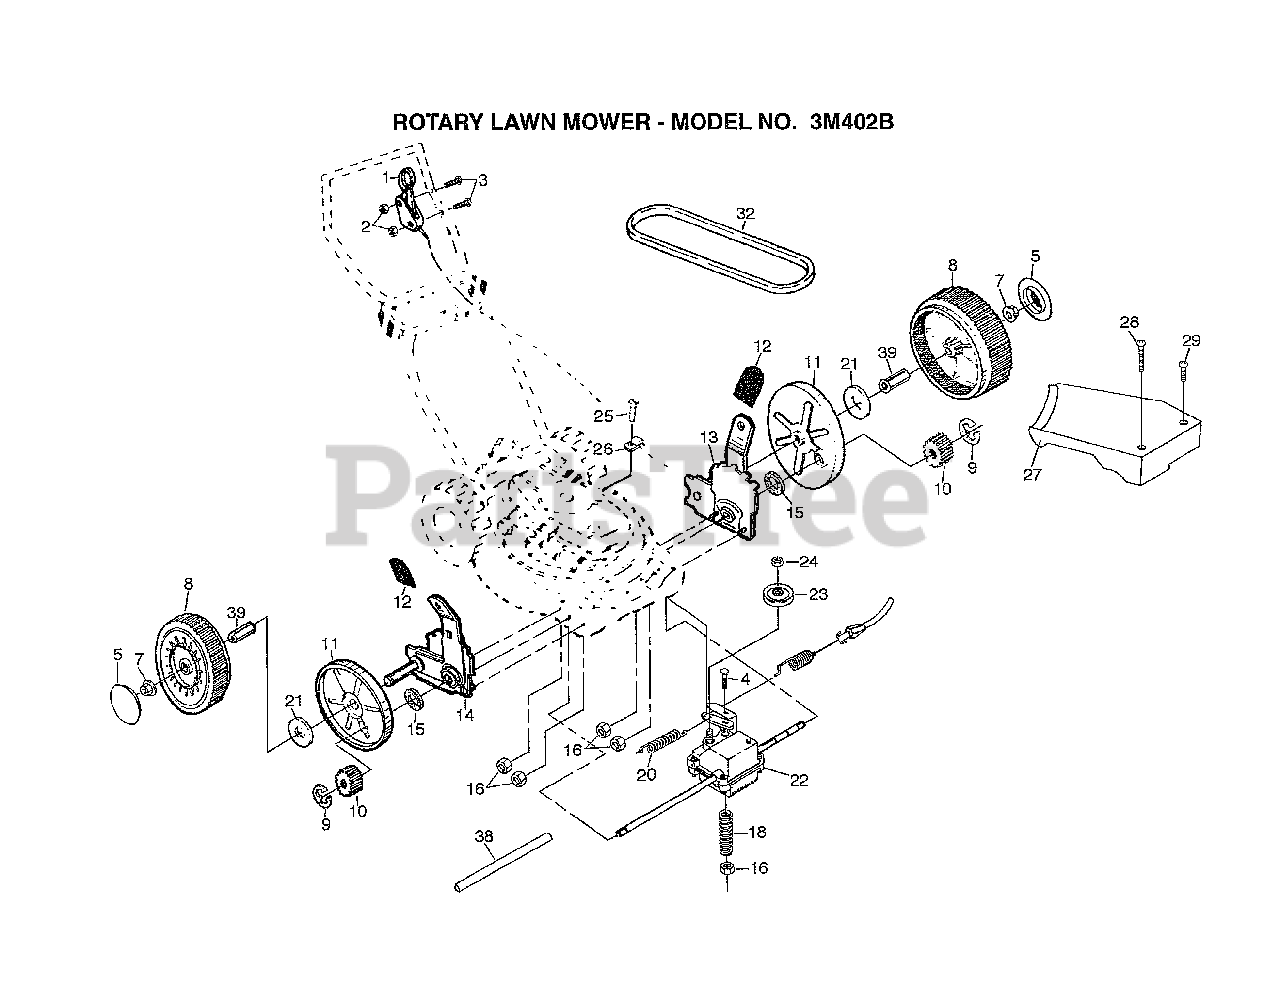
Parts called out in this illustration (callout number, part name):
1	CONTROL.DRIVE
2	LOCKNUT
3	SCREW
4	BOLT.1/4-20X2.0
5	HUB CAP
7	NUT.HXFLG.LOCK.
8	WHEEL.8X2.LP.PR
9	E-RING.7/16.RE.
10	PINION.GEAR
11	DUST SHROUD PM
12	KNOB PM
13	KIT.ADJ.ASM.LH.
14	KIT.ADJ.ASM.RH.
15	WASHER PM
18	SPRING.TENSION
20	SPRING
21	WASHER FLUT
23	PULLEY.DRIVEN
24	LOCKNUT
25	TAPPING SCREW
26	GUIDE CLIP PM
27	COVER DRIVE BLK
38	DRV SHAFT TUBE PM
39	BUSHING.HEX
